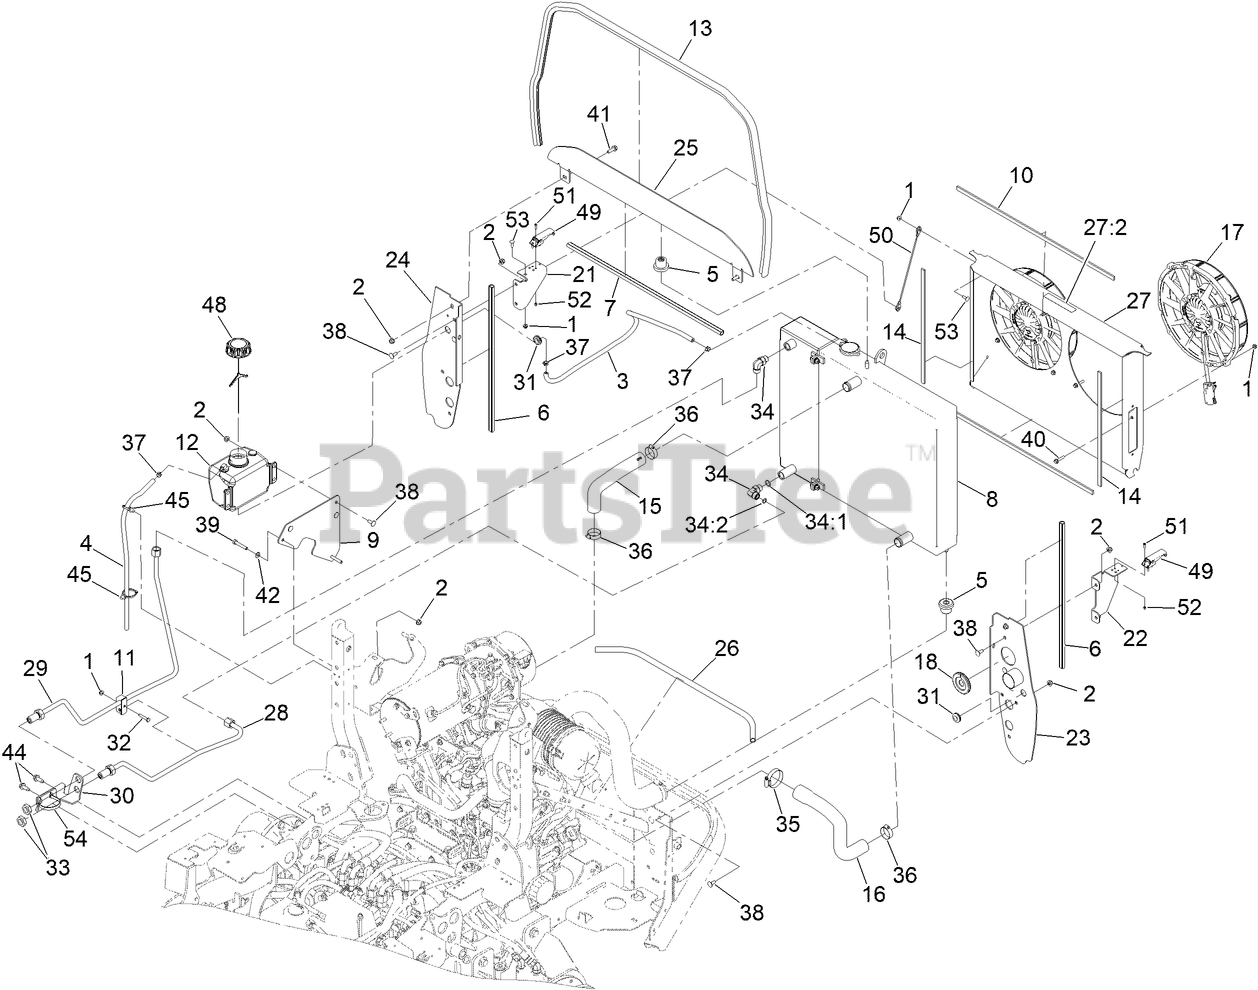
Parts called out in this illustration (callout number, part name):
1	NUT-HF
2	NUT-HF, NI
3	HOSE-FUEL
4	HOSE-FUEL
5	MOUNT-ISOLATOR
6	SEAL-BULB
7	SEAL-BULB
8	COOLING ASM
9	BRACKET-BOTTLE
10	FOAM-ADHESIVE BACKED
11	CLAMP-TWIN
12	TANK-OVERFLOW, W/CAP
13	SEAL-BULB
14	FOAM-ADHESIVE BACKED
15	HOSE-RADIATOR, UPPER
16	HOSE-RADIATOR, LOWER
17	FAN-12", 12V, ELECTRIC, REVERSING
18	GROMMET-SPLIT, 2.38 GD X 0.14 GW X 0.82
21	PLATE-RIGHT LATCH BRACKET
22	PLATE-LEFT LATCH BRACKET
23	SUPPORT-RADIATOR, LH [BLACK]
24	BRACKET-COOLING, RH
25	BRACKET-COOLING, TOP
26	SEAL-BULB
27	FAN SHROUD
27:2	DECAL-WARNING
28	HYDRAULIC TUBE ASM
29	HYDRAULIC TUBE ASM
30	PLATE-BULKHEAD
31	GROMMET
32	SCREW-HH
33	NUT-BULKHEAD
34	FITTING-ELBOW, 90 DEG
34:1	O-RING
34:2	O-RING
35	CLAMP-HOSE
36	CLAMP-HOSE
37	CLAMP-HOSE
38	SCREW-CARR
39	SCREW-HH
40	SCREW-HHF
41	SCREW-HHF
42	WASHER-PLAIN
44	SCREW-FORMING, THREAD
45	CLIP-TIE
48	CAP-W/TETHER
49	LATCH-DRAW
50	CABLE-STOP, SEAT
51	SCREW-BUTTON
52	NUT-LOCKROHS
53	BOLT-CARR
54	TIE-CABLE
